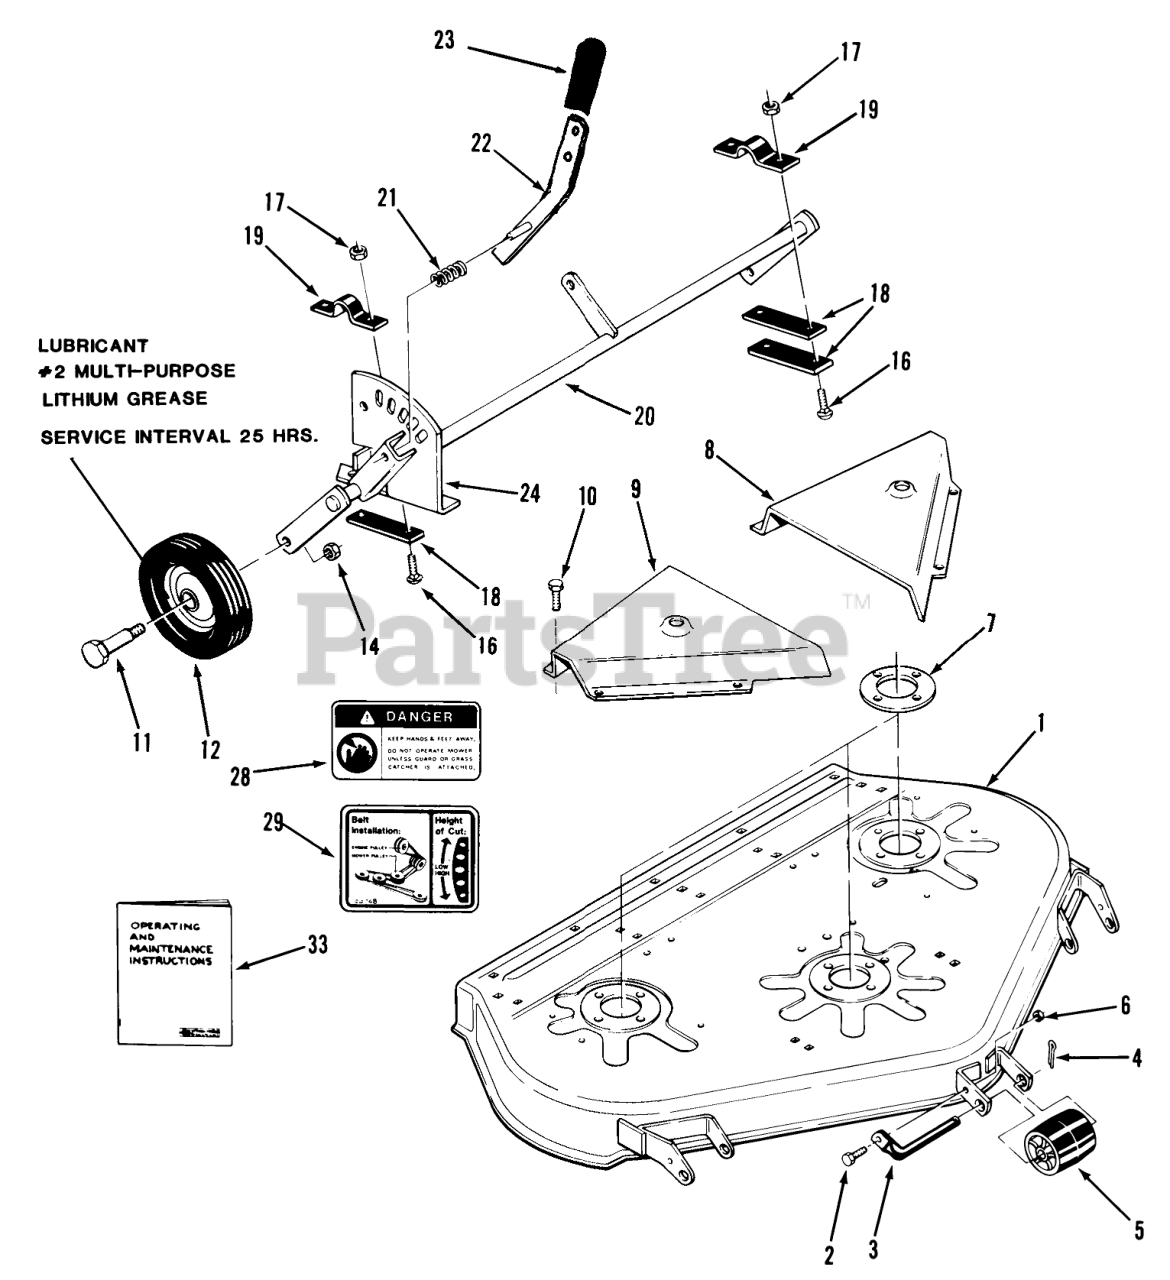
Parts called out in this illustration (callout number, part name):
1	Mower Deck
2	H H C S
3	ROLLER-SHAFT
4	Cotter Pin
5	Roller
6	Nut
7	PLATE-SPINDLE
8	Belt Cover LH
9	Belt Cover RH
10	Bolt
11	BOLT-SHOULDER
12	WHEEL
14	Nut
16	Bolt
17	Nut
18	Bar
20	ASSY GAUGE WHEEL R
21	SPRING-COMPRESSION
22	Lever
24	Quadrant
28	Danger Decal
29	Decal-Height Adj. & Belt Diagram
33	Operating and Maintenance Instructions
